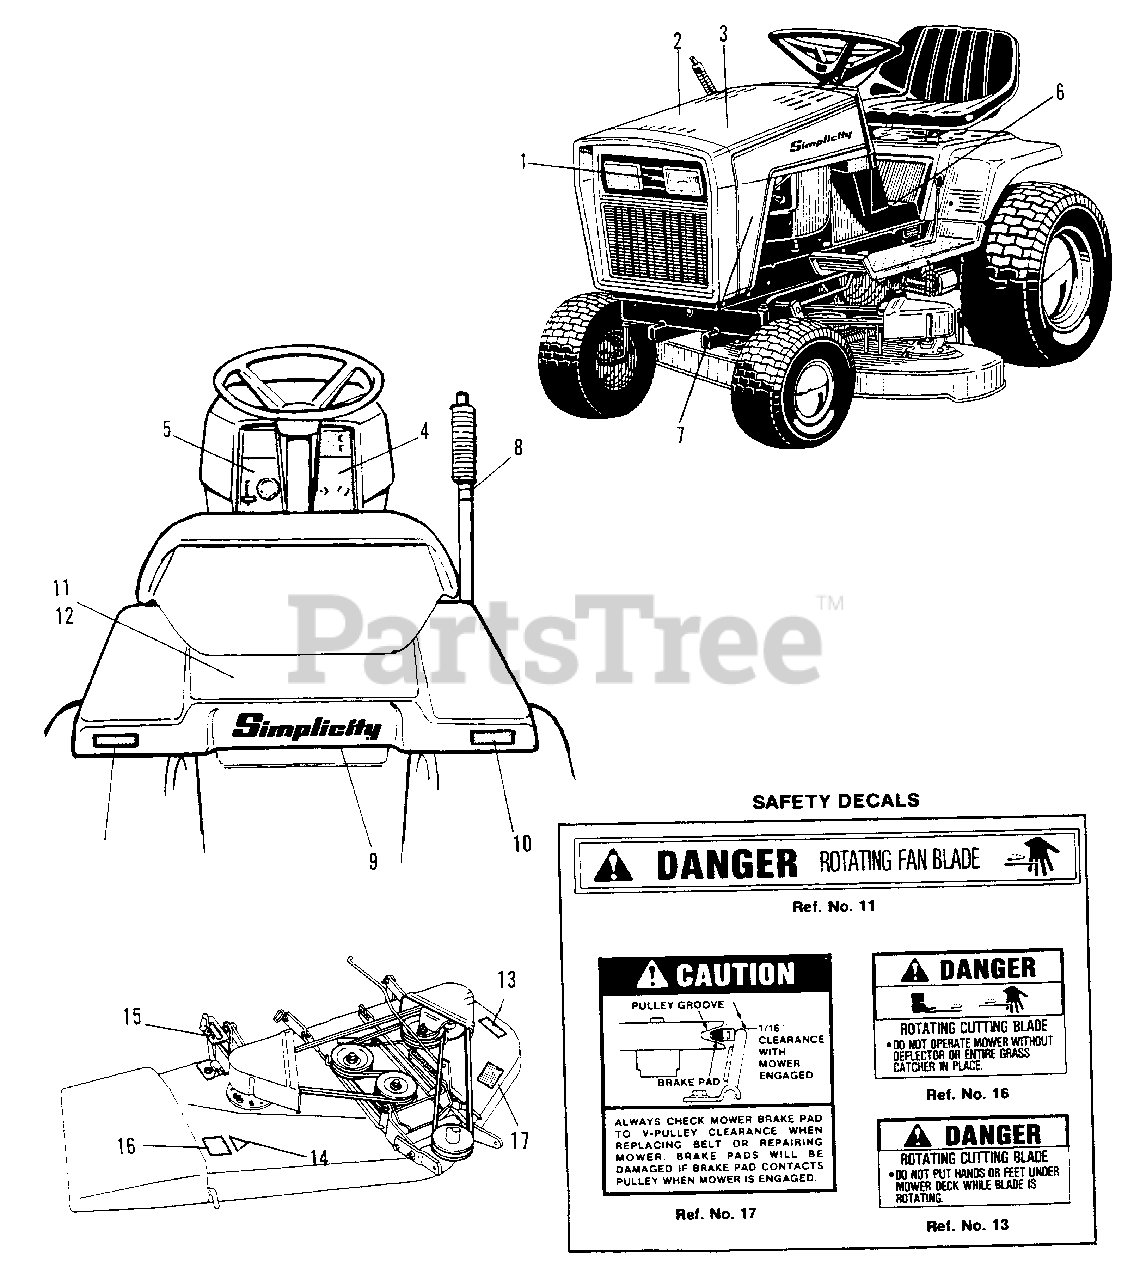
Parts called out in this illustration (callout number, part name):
1	DECAL, Grille
2	DECAL, Hood Stripe, R.H. (12.5 HP)
2	DECAL, Hood Stripe, R.H. (16 HP)
2	DECAL, Hood Stripe, R.N. (17 HP)
3	DECAL, Drive Belts (1691263, 1691468)
3	DECAL, Drive Belts (1691736)
4	DECAL, Dash, R.H.
5	DECAL, Dash, L.H.
6	DECAL, Shift Pattern
7	DECAL, Hood Stripe, L.H. (12.5 HP)
7	DECAL, Hood Stripe, L.H. (16 HP)
7	DECAL, Hood Stripe, L.H. (17 HP)
8	DECAL, Lift Lever
9	DECAL, "Simplicity"
10	REFLECTOR, Rear
11	DECAL, Warning, Fan (Under Seat Deck)
12	DECAL, Release Valve (Under Seat Deck)
13	DECAL, Danger
14	DECAL, OPEI
15	DECAL, Mower Height
16	DECAL, Danger
17	DECAL, Caution, Blade Brake
